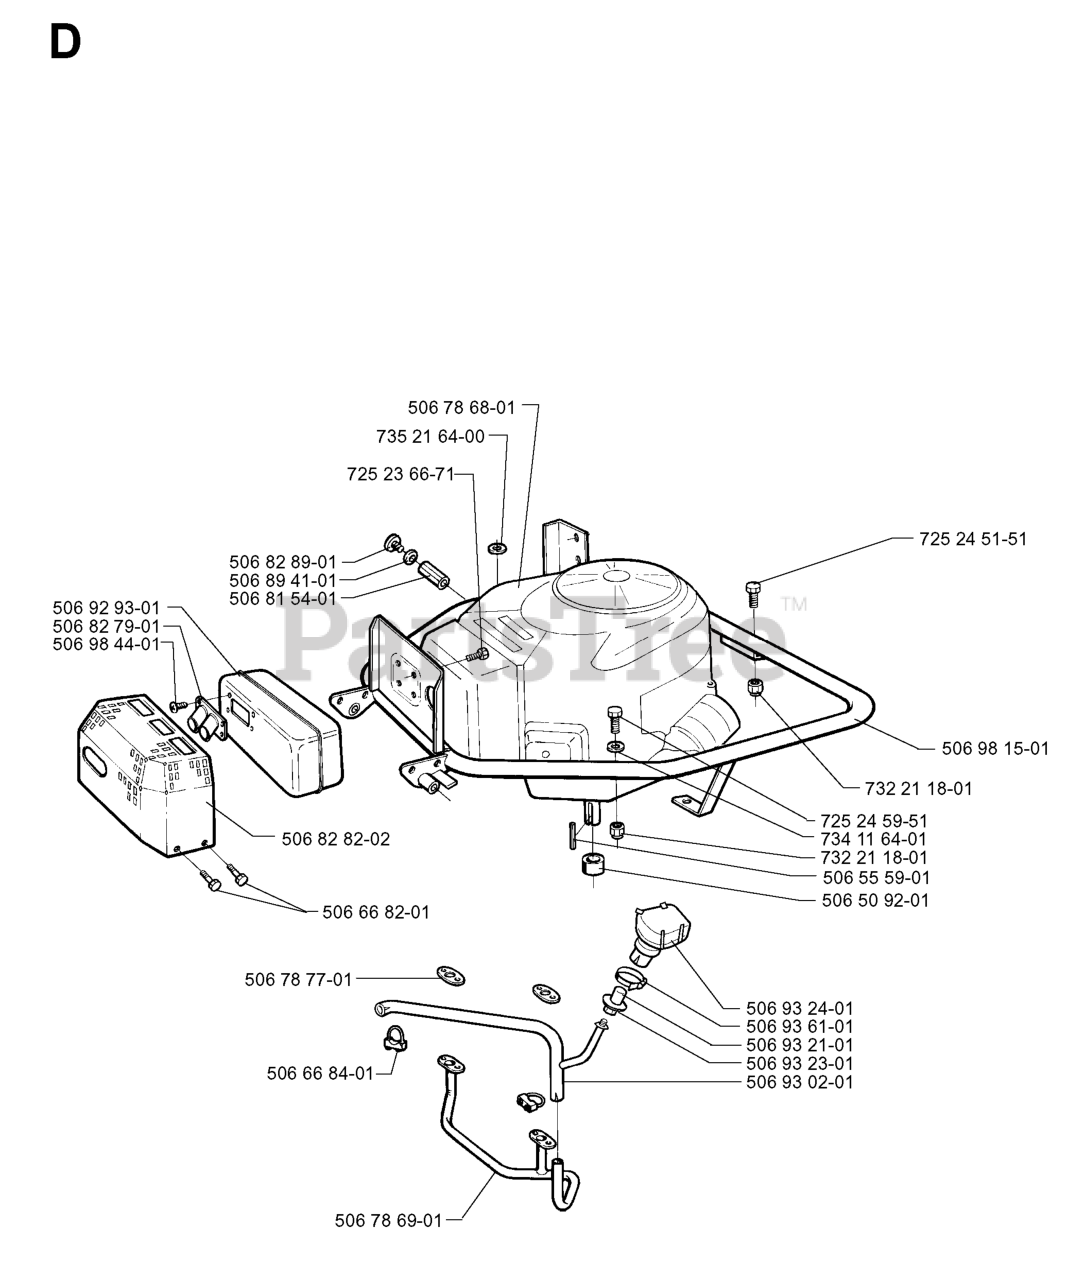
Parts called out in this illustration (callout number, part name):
1	Battery 12 Volt 25 Amp
2	BOLT.HEX.1/4.X.3/4.DICHROMATE
8	BOX.BATTERY.MOUNT.FRONT.LT
16	SWITCH INTERLOOK PUSH-IN
21	HARNESS.LIGHT W/4152J BULBS
24	CABLE.BATT.POS.WIRE.TG.DA SOL
25	CABLE.STARTER.6G.BL/RED.17.5
26	FUSE 20AMP
27	NUT
28	CABLE GROUND 6 GA 21" 90T BLK
29	SWITCH.SEAT.DELTA.OPC.
30	SWITCH.IGN.DELTA.W.LGH.ROS
33	KEY.CHAIN.BLISTER.PACK.GEN.USA
40	HARNESS.IGN.DASH.HUQ/P
41	SCREW
42	TERMINAL COVER
43	SOLENOID.W/BRASS.PLUNGER
46	RP.GUAGE.SRVCMNDR.HRMTR.
50	RP.PTO.SWITCH.8 TERMINAL.BLACK
55	SCREW 5/16"
59	OUTLET.12-VOLT
71	HARNESS-CHASSIS SUB
79	BULB HOLDER ASM.
90	COVER.TERMINAL.BATTERY
91	STRAP.BATTERY.MOUNT.FRONT(2 2)
92	HARNESS.PIGTAIL.CONSLE
93	SCREW.PLASTITE
94	MODULE.REVERSE.ROS
99	SCREW HEXWSHR 1/4-20X3/4
103	HARNESS PIGTAIL 12V OUTLET
